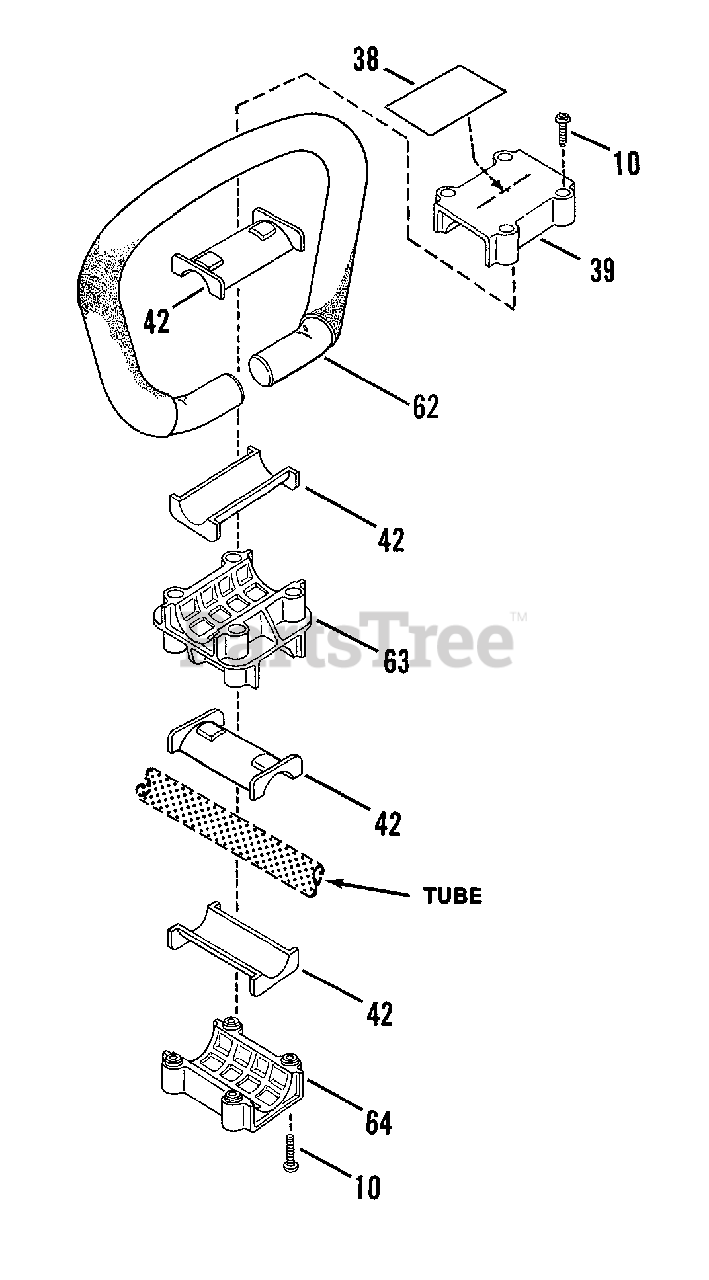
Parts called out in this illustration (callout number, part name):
10	SCREW, #10-16x3/4"
38	DECAL, Replacement Part
39	HANDLE MOUNT ASSEMBLY
42	ISO-MOUNT
62	HANDLE ASSM'Y., Loop
63	HANDLE MOUNT, Center
64	HANDLE MOUNT, Cap
